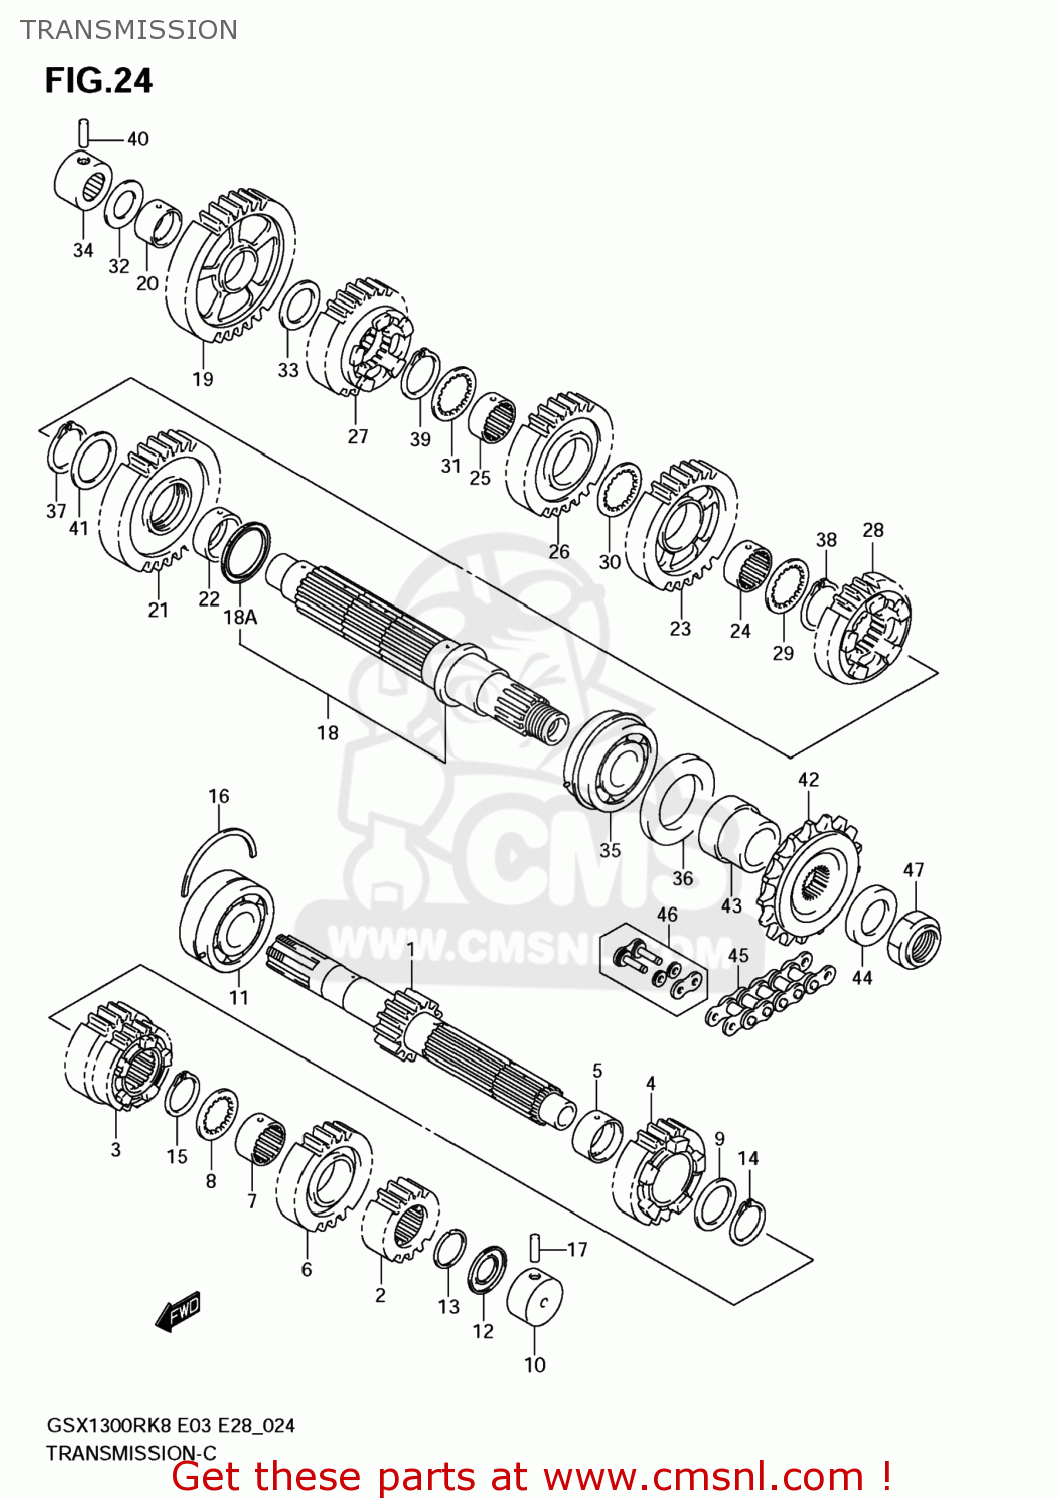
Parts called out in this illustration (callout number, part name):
1	SHAFT,COUNTER
2	GEAR,2ND DRIVE
3	GEAR,3RD & 4TH DRIVE
4	GEAR,5TH DRIVE
5	BUSH,5TH DRIVE GEAR
6	GEAR,6TH DRIVE
7	BUSH,6TH DRIVE GEAR
8	WASHER,LOCK
9	SHIM(27X36X2.5)
10	BEARING(20X34X17.5)
11	BEARING(25X62X25.4)
12	SEAL,OIL(20X31.2X2.7)
13	CIRCLIP
14	CIRCLIP
15	CIRCLIP
16	C RING
17	PIN
18	SHAFT,DRIVE
18A	RING,DRIVE SHAFT FRICTION
19	GEAR,1ST DRIVEN
20	BUSH,1ST DRIVEN GEAR
21	GEAR,2ND DRIVEN
22	BUSH,2ND DRIVEN GEAR
23	GEAR,3RD DRIVEN
24	BUSH,DRIVEN GEAR
25	BUSH,DRIVEN GEAR
26	GEAR,4TH DRIVEN
27	GEAR,5TH DRIVE
28	GEAR,6TH DRIVEN
29	WASHER,LOCK
30	WASHER,LOCK
31	WASHER,LOCK
32	SHIM(20X34X1)
33	SHIM(24X34X1)
34	BEARING(20X34X20)
35	BEARING(30X62X23.8)
36	SEAL,OIL(42X62X7)
37	CIRCLIP
38	CIRCLIP
39	CIRCLIP
40	PIN
41	WASHER
42	SPROCKET,ENGINE(18T)
43	SPACER,ENGINE SPROCKET NO.1
44	SPACER,ENGINE SPROCKET NO.2
45	CHAIN,DRIVE
46	JOINT SET,CHAIN
47	NUT
